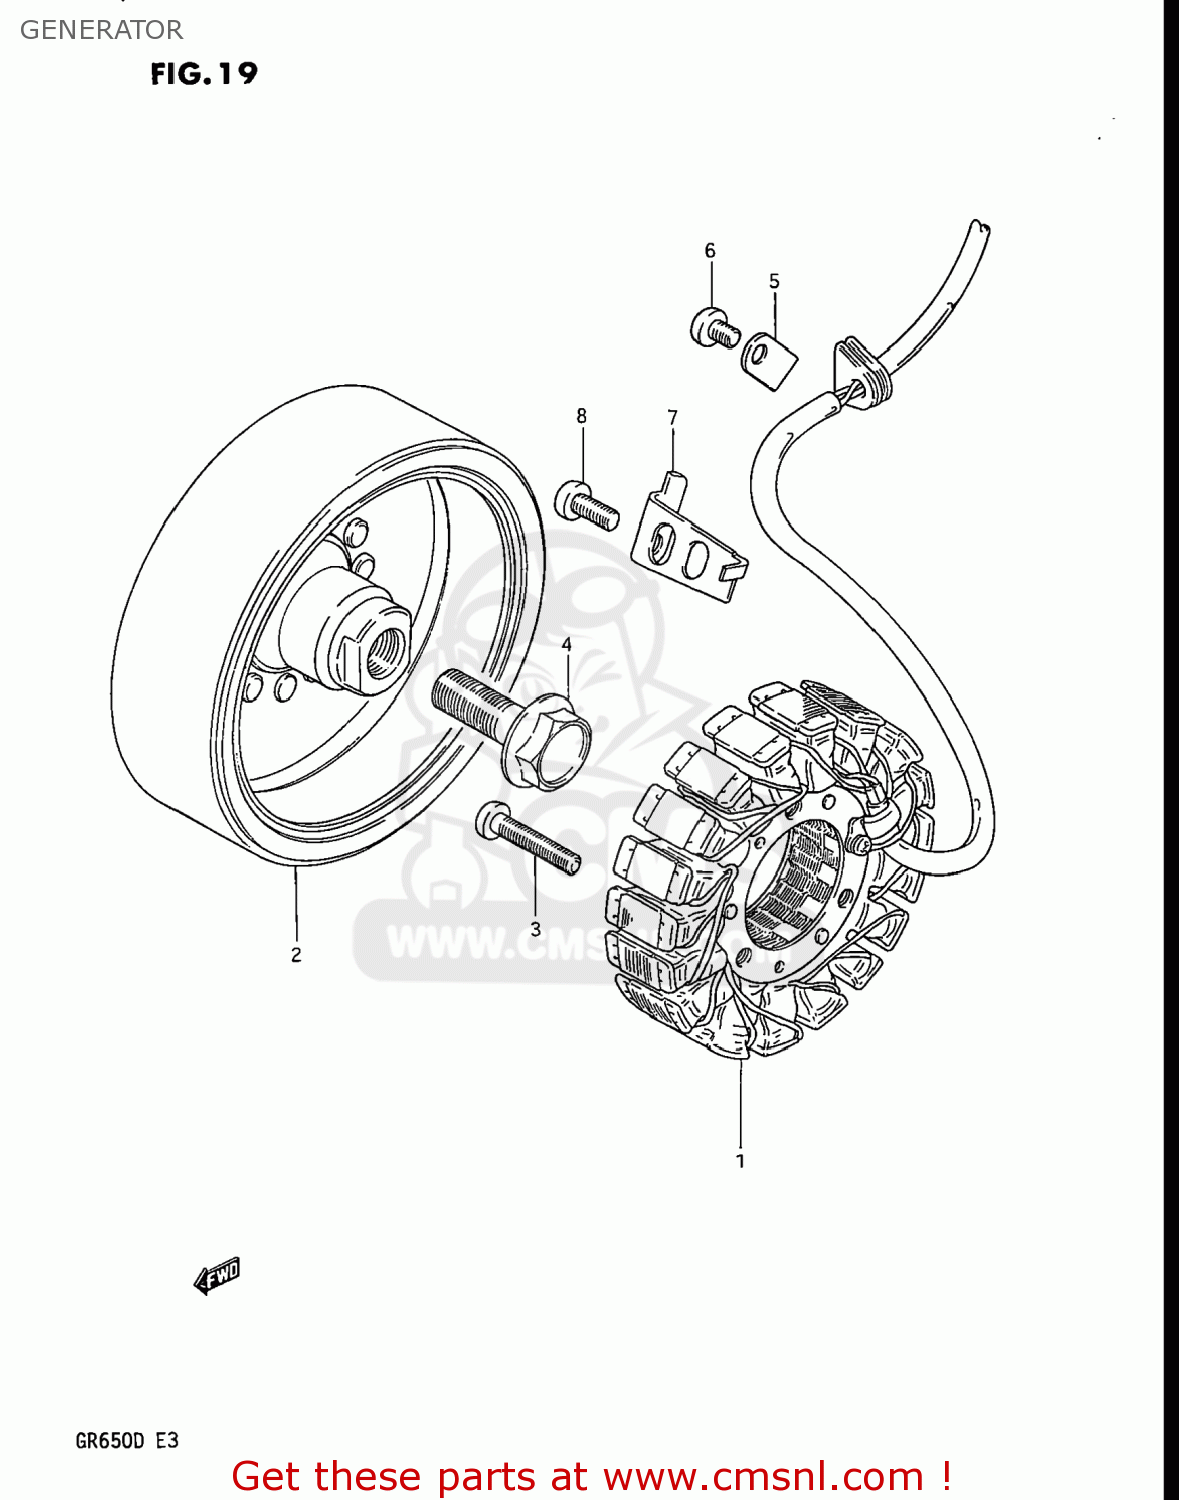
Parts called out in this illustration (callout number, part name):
1	STARTER ASSY
2	ROTOR ASSEMBLY
3	SCREW
4	BOLT(12X40)
5	CLAMP,GENERATOR LEAD WIRE
6	SCREW
7	CLAMP,GENERATOR LEAD WIRE
8	SCREW
